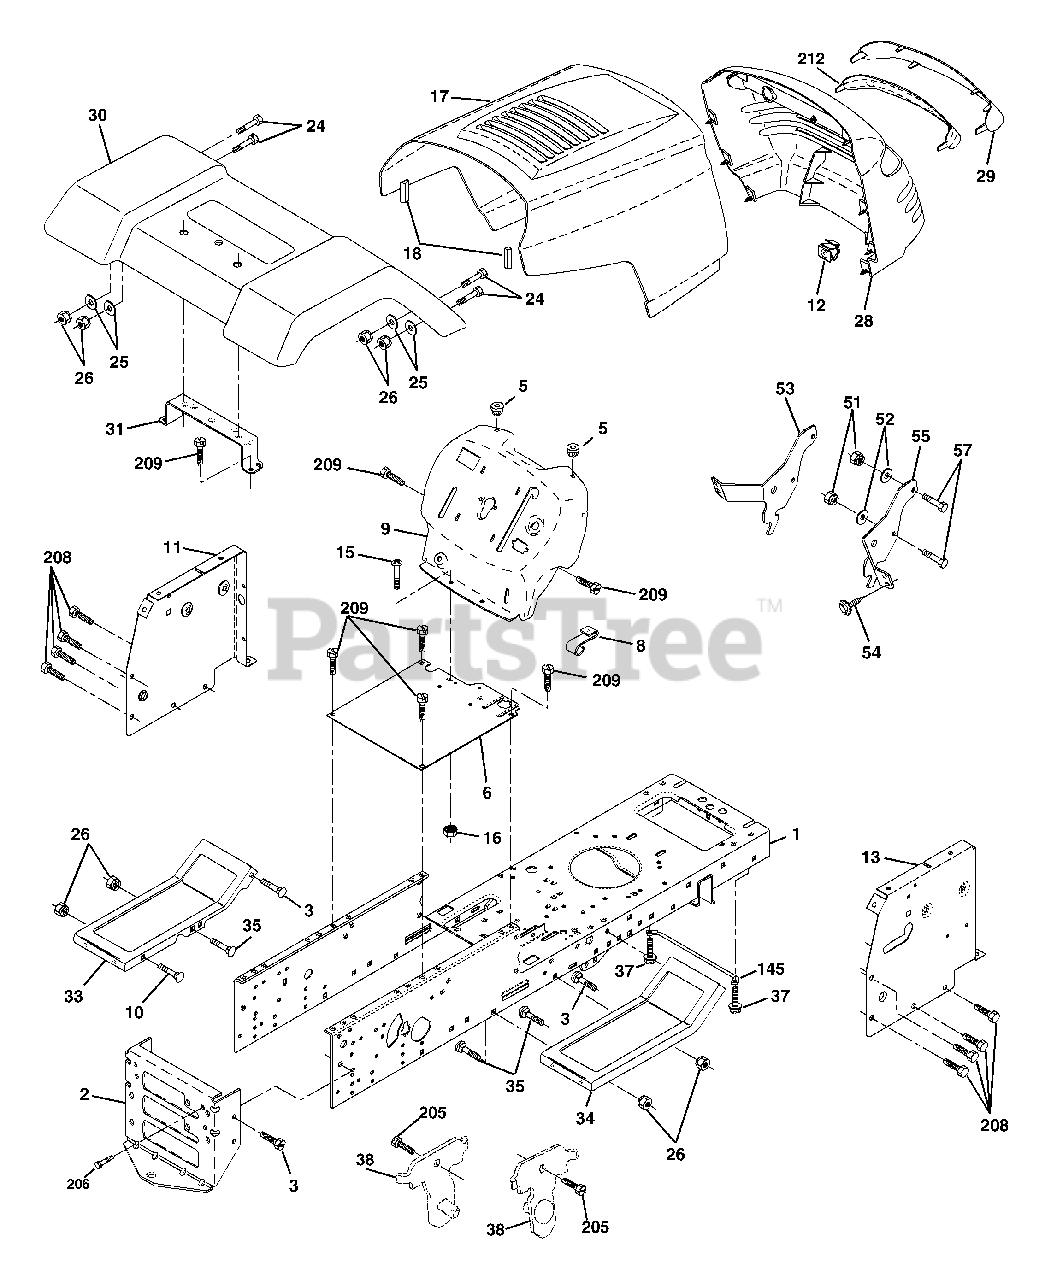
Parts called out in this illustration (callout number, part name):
1	Chassis
2	Drawbar, Stretch
3	Screw 3/8-16 x 3/4
5	Bumper, Hood/Dash
6	Saddle Silkscreen
8	Clip Retainer Slide-On
9	Dash
10	Bolt, Carriage 3/8-16 x 1
11	Panel Dash LH
12	Clip Tinnerman Grille P.L
13	Panel Slkscr Dash RH
15	Screw Mach TRHD 5/16-18 Unc x 3/4
16	Nut Keps 5/16-18 Unc
17	Hood
18	Bumper Hood
24	Bolt Fin Hex 3/8-16 Unc x 1 Gr. 5
25	Washer 13/32 x 13/16 x 12 Ga
26	Nut Lock Hex w/Ins 3/8-16 Unc
28	Grille/Lens Asm.
29	Lens Grille Private Label
30	Fender
31	Bracket Fender Repl 109873x
33	Footrest Pnt LH
34	Footrest Pnt RH
35	Bolt Rdhd Sht Sqnk 3/8-16 x 3/4
37	Screw Thdrol 5/16-18 x 1/2 TYT
38	Bracket Asm. Pivot Mower
51	Nut Lock W/Insert 1/4-20 Unc
52	Washer 9/32 x 7/8 x 16 Ga.
53	Bracket Grille Lh
54	Screw Hex 8-18 x 7/8
55	Bracket Grille Rh
57	Bolt Fin Hex 1/4-20 Unc x .75
145	Rod Pivot Chassis/Hood
205	Screw Thdrol 3/8-16 x 1/2
206	Bolt Shoulder 5/16-18
208	Screw Thdrol 3/8-16 x 1/2
209	Screw Hex Wsh Thdrol 3/8-16
212	Insert Lens Reflect
